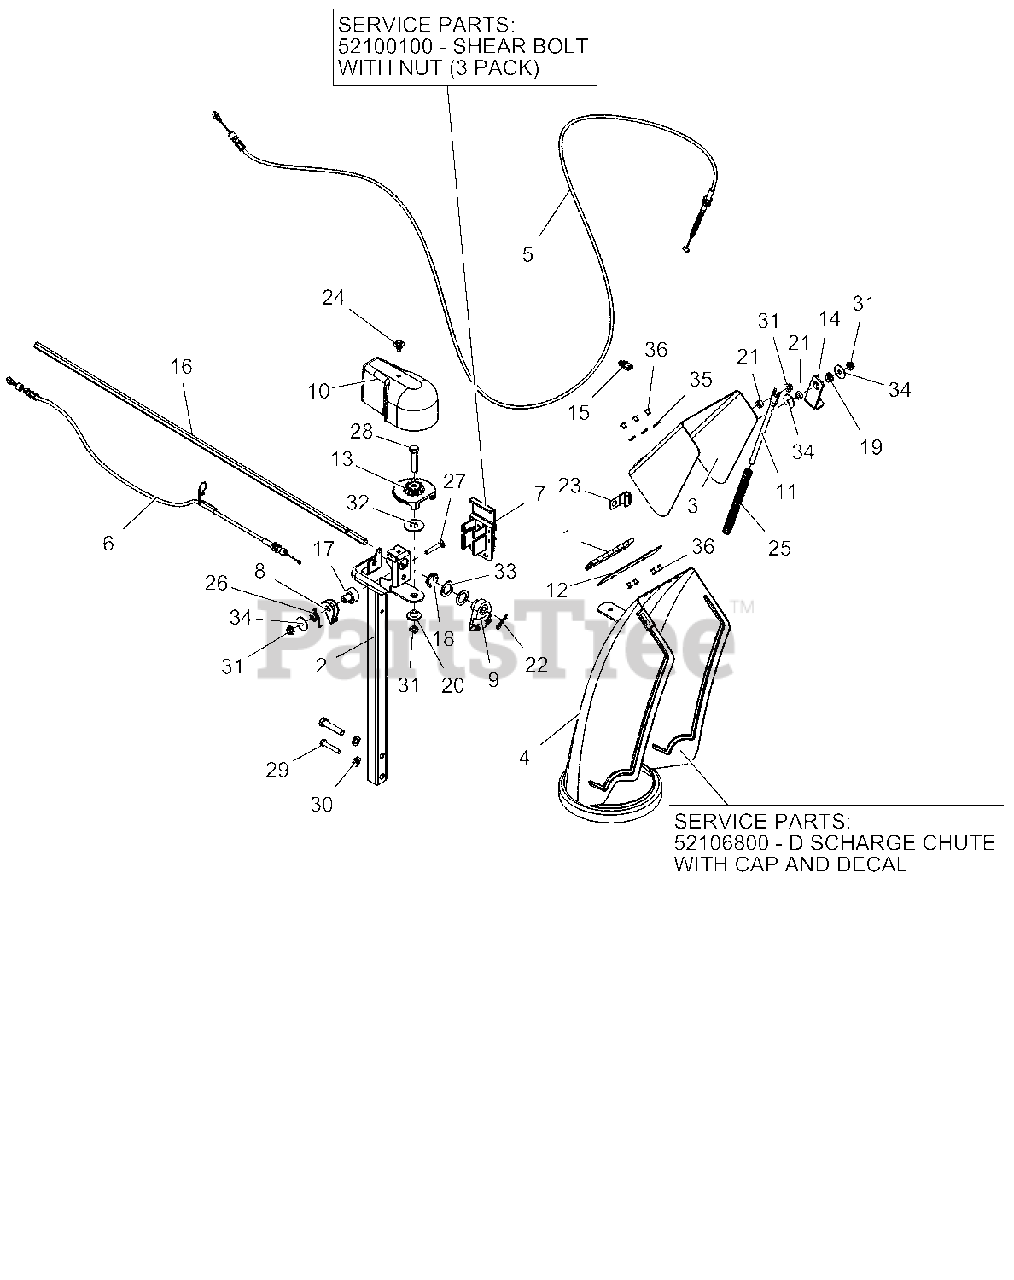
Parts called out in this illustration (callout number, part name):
2	PEDESTAL, CHUTE - QUICK STICK
3	CAP,LARGE,REMOTE
4	CHUTE,DISCHARGE,NOTCHED,QT
4	KIT, DISCHARGE CHUTE W/DEF QT2
5	CABLE, DEFLECTOR - DELUXE
6	CABLE,CHUTE LOCK,PLAT/SHO
7	SHEAR BOLT SERVICE ASSEMBLY
7	HOLDER W LARGE SHEAR BOLT /NUT
8	ARM, LOCKING
9	GEAR, CHUTE-ACTUATION
10	COVER, CHUTE GEAR
11	ROD, DEFLECTOR CAP
12	CAP SEAL 5.50
13	GEAR, CHUTE
14	BRACKET, CABLE ANCHOR
15	CLIP, CABLE GUIDE
16	ROD, HEX - CHUTE ROTATION
17	BUSHING, LOCK ARM
18	BUSHING, POLYLINER-.75 SNAPIN
19	BUSHING, POLYLINER-.50 SNAPIN
20	BSHG-FLG .265X.477X.375X1.00
21	BSHG-SLV .265X.500X.219
22	PIN-HAIR INT .08X.18X1.18 YWZC
23	J-CLAMP
24	SCR-TAP .25-20X.50 LGHWH TR YZ
25	SG-COMP .08X.40X6.50 14#/IN
26	SG-TORS
27	@BLT-RDHDSQNK .25-20X1.50 G5YZ
28	@BLT-HEX .38-16X1.75 GR5 YWZC
29	@BLT-HEX .25-20X1.50 GR5 YWZC
30	@WSHR-LK .38X.094 REG YWZC
31	@NUT-LK-CTR-FLG .25-20 YWZC
32	WSHR-FLT-NYL .515X1.375X.093
33	WSHR-FL-STL.754X1.125X.062YWZC
34	WSHR-FL-STL .281X1.000X.063
35	WSHR-FL-STL .196X.500X.06 YZ
36	RVT-POP .187 YZ
